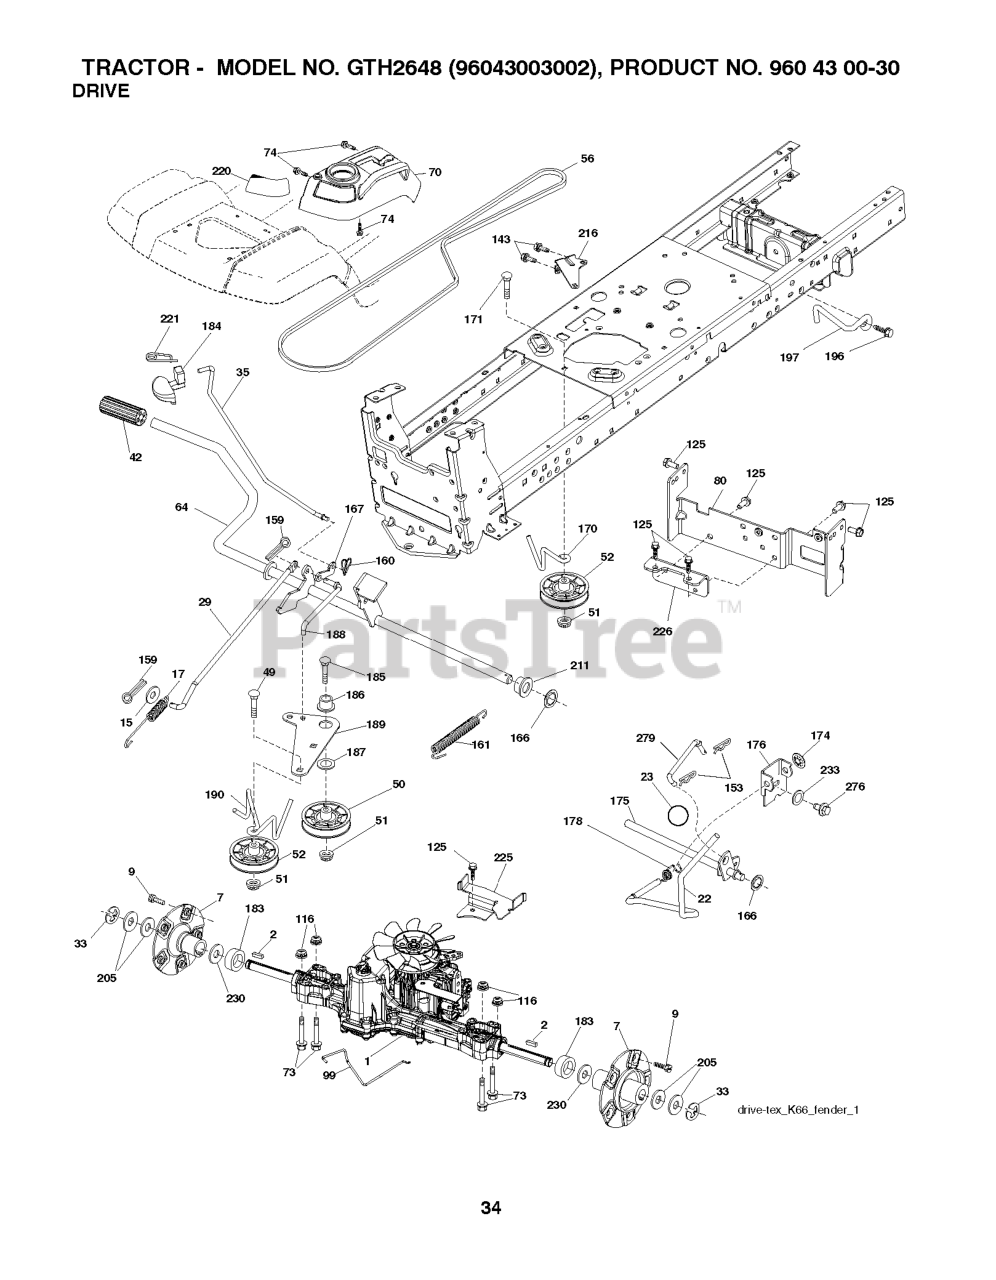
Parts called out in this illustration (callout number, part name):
1	TRANSAXLE.K66.AD.FCH.TG
2	KEY 1/4 X 2.5
7	HUB.ASM.WHEEL.REAR.23"TEX
15	WASHER
17	SPRING.BRAKE.K46
22	ROD.SHIFT.FENDER.STGT.
23	KNOB.DELUXE.(PISTOL.GRIP).BLAC
29	ROD.BRAKE.K66
33	E RING HYT
35	ROD.BRAKE.PARKING.GT.H
42	PEDAL COVER T
50	IDLER.FLAT.910.OFFSET
51	NUT LOCK FLG 3/8-16 UNC
52	IDLER.V-GROOVE.910.OFFSET
64	SHAFT.ASM.PEDAL.BRAKE.
70	RP CONSOLE.ASM.HYDO.HUSQ.
73	BOLT HEX 5/16-18 GR 5
74	SCREW.HI-LO.CONSOLE
80	STRAP.TORQUE.K66
99	ROD.SPRING.BYPASS.K66.GT.Z
116	NUT LOCK HEX FLANGE 5/16-18
125	SCREW
143	Screw 5/16-18 x 1/2 Hex, Self Tapping 5/16-18 x 1/2
153	RETAINER M
159	COTTER PIN
160	RETAINER CLIP
161	SPRING, RETURN LT
166	NUT.PUSH.625.2006
167	LATCH.BRAKE.SPRING
170	KEEPER.V-IDLER.CENTER.
174	NUT.PUSH.500.2006
175	SHAFT.ASM.SHFT.T2.TLT
176	ARM.CLEVIS.ROD.SHIFT
178	SPRING.SHIFT.GT2006
183	SPACER.AXLE.HG.TEX
184	HANDLE.PARKG.BRK.HUSQ X667
186	SPACER.RETAINER
187	WASHER 12/32X2X10GA
188	RP.LINK.CLUTCH.GROUND.DRIVE
189	BELLCRANK.GROUND.DRIVE.TEX.
190	KEEPER.BELLCRANK.DRIVE
196	SCREW 3/8-16X1
197	BRKT.ANIT-ROTATION.CLUTCH
211	BUSHING.SHAFT.BRAKE.HAND
216	BRACKET.PULLEY.IDLER.W/TEX
220	REFLECTOR.RH.TEX GT
221	RETAINER.SPRING.CLIP.H
225	KEEPER.BELT.TRANSAXLE.K66
226	BRACKET.MOUNT.TORQUE.K66.TG
233	WASHER SERRATED
276	BOLT FIN HEX 7/16-14 X 1
279	LINK.ASM.SHIFT.FENDER.K66
